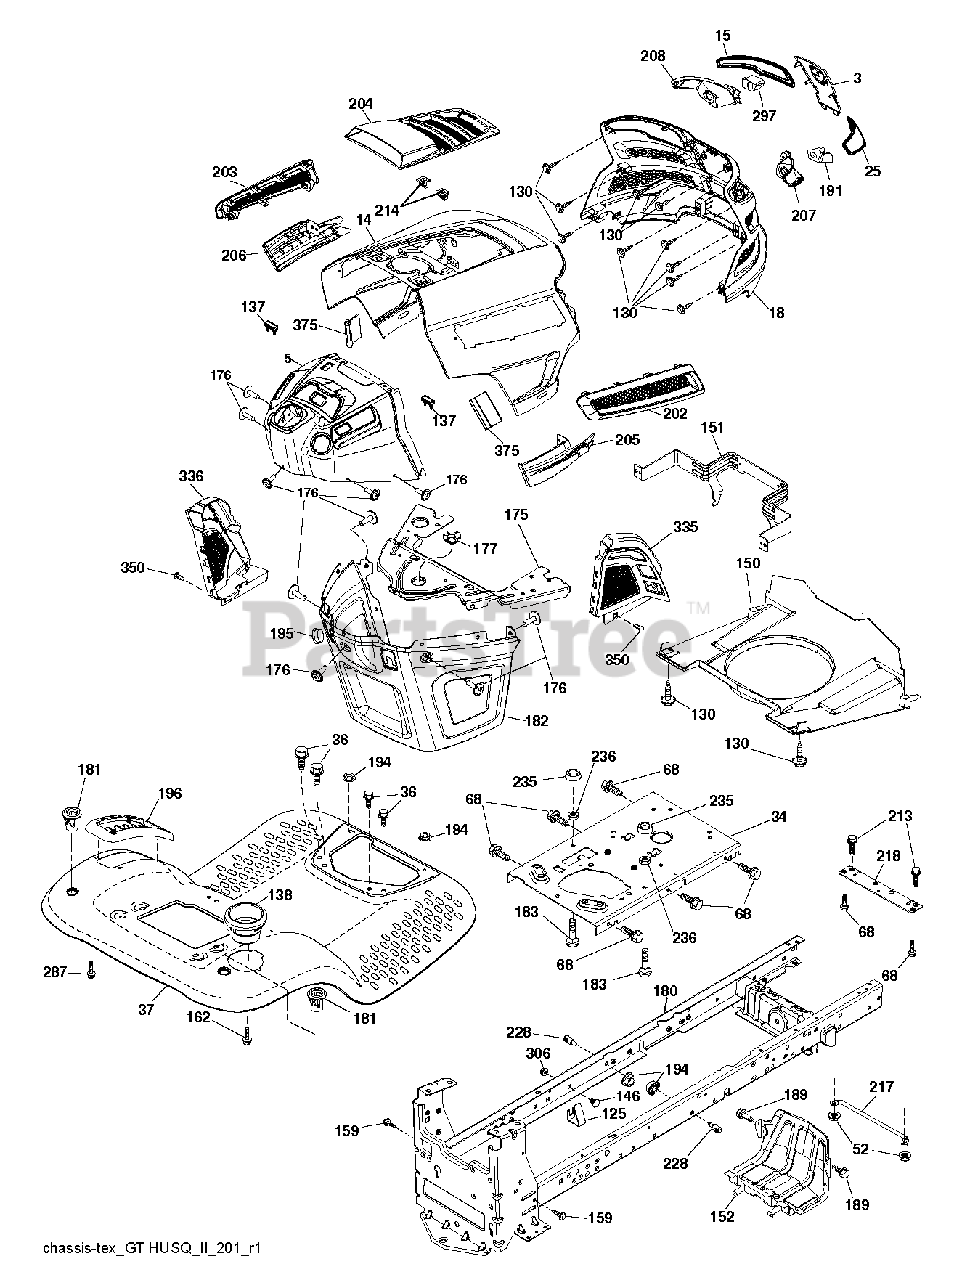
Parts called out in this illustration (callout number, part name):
3	APPLIQUE.SUBASM.GT.HUSQ.II
5	UPPER.GT2.SVC.MINDING.C-O.M;H
14	HOOD.ASM.HUSQVARNA.GT.TEX.ORAN
15	LENS.HEADLIGHT.LH.GTII.2011
18	GRILLE.SUBSTRATE.2011.
25	LENS.HEADLIGHT.RH.GTII.2011
34	PLATE.ENGINE.WELDED.CHASSIS
36	SCREW 5/16"
37	FENDER.TLT.PDL.CNTRL.W/CPH.ORG
52	LOCKNUT
68	SCREW LT
125	CLIP.FUEL.LINE
130	SCREW.#10 X 0.750.BOS
137	BUMPER DASH
138	HOLDER.CUP.LT.GREY
146	BOLT.RDHD.SHT.SQNK.3/8-16X5/8
150	AIR.DUCT.GTV2(2.54"RING HEIGHT
151	BRACKET.PIVOT.HOOD.GT.HUSQ.II
152	SHIELD.BROWNING.PNT.GT.V2
159	SCREW, 3/8-16X3/4
162	SCREW.HI-LO.CONSOLE
175	PLATE.CROSSMEMBER.HUSQ
176	SCREW.#10-24X5/8.RN.QU
177	BUSHING STEERING
180	CHASSIS
181	BUSHING.MNT.FEND.CRGO.TEX.49
182	DASH LOWER.HUSQ.PRED NO CRUISE
183	BOLT.5/16-18X1-1/4 FULL THD
189	SCREW
191	INSERT.REFLECTIVE.RH.HUSQ.GTII
194	NUT LOCK HEX FLANGE 5/16-18
195	PLUG.HOLE.DASH.LOWER.12V.BLK
196	DECKLFT.CONSOL FULL ASSM GREY
202	VENT.SIDE.RH.GT.HUSQ.II.
203	VENT.SIDE.LH.GT.HUSQ.II.498
204	VENT.TOP.HUSQ.GT2
205	SIDE.TRIM.RH.GT.HUSQ.II
206	SIDE.TRIM.LH.GT.HUSQ.II.GRAY
207	BEZEL LIGHT.RH.GT.II.MYLAR
208	BEZEL LIGHT.LH.GT.II.MYLAR
213	BOLT
214	CLIP.RETAINER.TINNER.
217	ROD.PIVOT.HOOD
218	X-PIECE.HOOD.STOP.NON/
228	STUD.FASTNER.W/ANTI-ROTATE
235	SPACER FENDER
236	NUT.CENTERLOCK.5/16-
287	SCREW 1/4X20
297	INSERT.REFLECTIVE.LH.HUSQ.GTII
306	NUT LOCK FLG 3/8-16 UNC
335	COVER.LOWER.DASH.RH.BLACK
336	COVER-LH.LOWER.DASH.GT2.BLACK
350	CLIP.X-MAS.TREE
375	BUMPER CLIP-ON. DASH 1"
